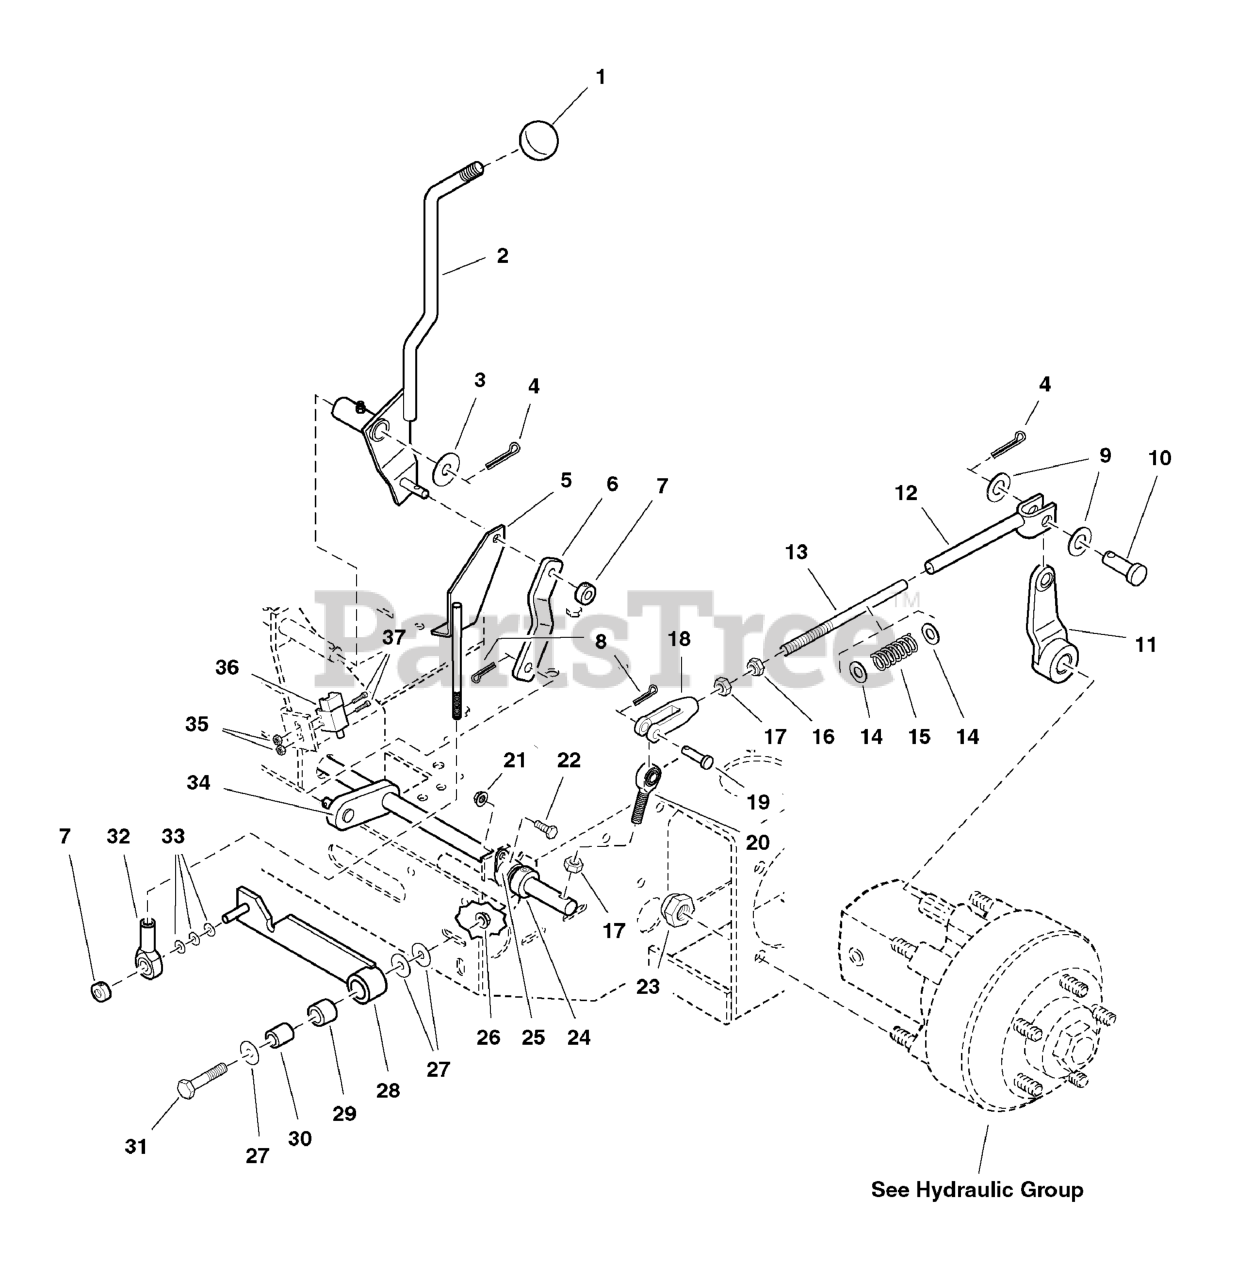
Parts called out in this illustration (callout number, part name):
1	KNOB
2	PARKING BRAKE LEVER
3	WASHER, 5/8" SAE
4	PIN, COTTER, 1/8 X 1-1/4
5	BRAKE LOCK LINK
6	BRAKE LINK
7	COLLAR, 5/16" Set
8	PIN, 3/32 X 0.750, COT, ZINC/CLEAR
9	WASHER, 1/2 SAE
10	CLEVIS PIN, 1/2" x 1-1/4"
11	BRAKE LEVER
12	BRAKE TUBE
13	BRAKE SPRING ROD
14	WASHER, 3/8 SAE
15	SPRING, Compression
16	NUT, 3/8-24 Hex Nylon Lock
17	NUT, 3/8-24 Hex
18	CLEVIS, 3/8-24, Plastic
19	CLEVIS PIN, 3/8 x 1-1/8
20	BALL JOINT, 3/8-24 Male
21	NUT, 1/4-20 HEX SERR. FLANGE
22	BOLT, 1/4-20 x 3/4
23	NUT, Hex, Nylon Lock, 1/2-20
24	COLLAR, 5/8" Set
25	5/8" Triangle Bearing
26	NUT, 5/16-18 HEX SERRATED FLANGE (LARGE)
27	WASHER, 5/16" Fender
28	NEUTRAL LOCK LEVER, Complete
29	BUSHING, Brass
30	SPACER, .32 x .75 x 1.06
31	BOLT, 5/16-18 x 2
32	BALL JOINT 5/16-24 RH FEMALE BRONZE RACE
33	WASHER, 5/16" SAE
34	BRAKE SHAFT
35	NUT, #10-24 Hex
36	SWITCH, PLUNGER, N.O./N.C.
37	SCREW, #10-24 x 3/4
